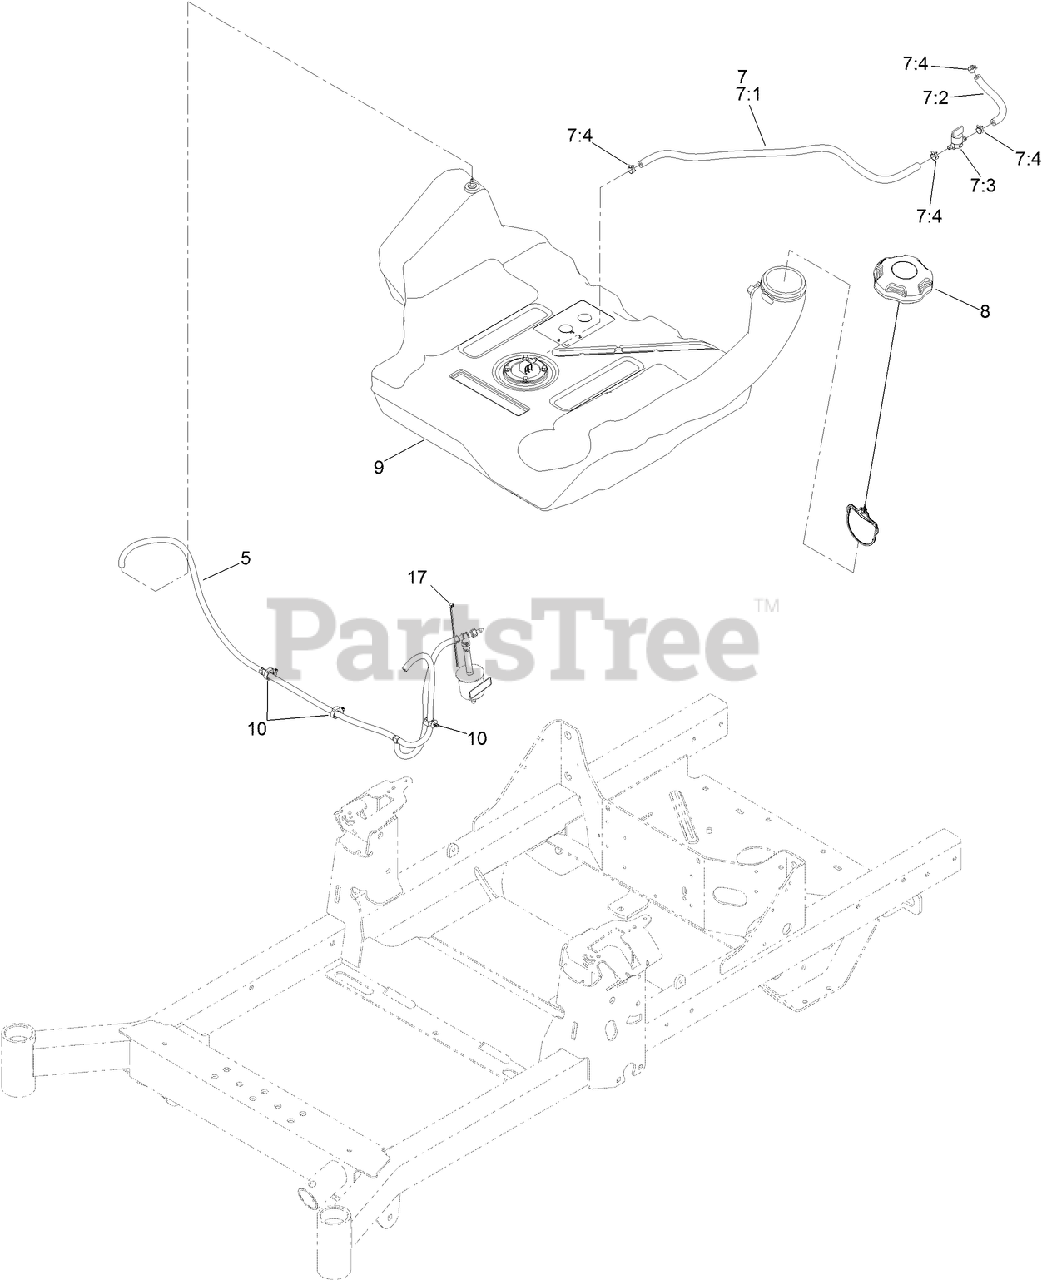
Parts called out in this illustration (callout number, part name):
5	VENT HOSE ASM
7	FUEL HOSE ASM
7:1	HOSE-FUEL
7:2	HOSE-FUEL
7:3	VALVE-FUEL
7:4	CLAMP-HOSE
8	CAP-FUEL
9	TANK-FUEL
17	TIE-CABLE
